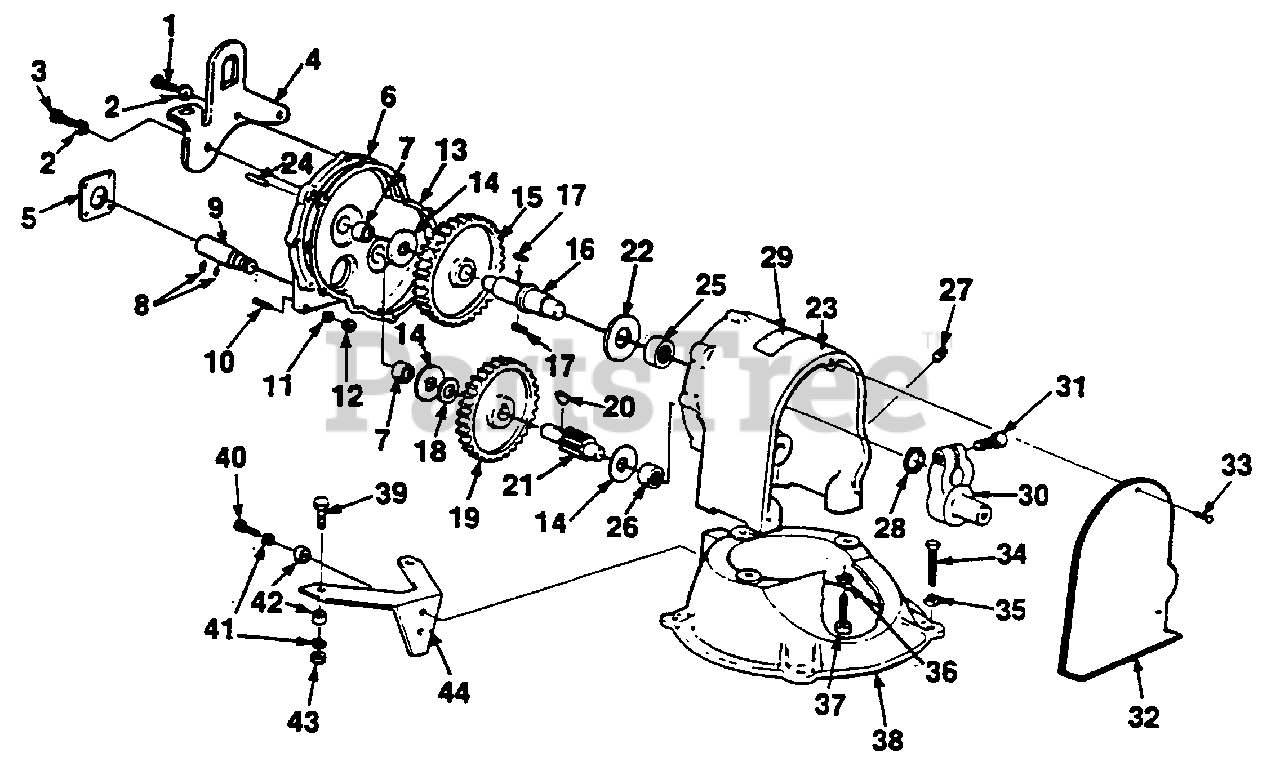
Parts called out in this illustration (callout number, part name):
1	SCREW-Hex hd. (1/4-20 x 1 1/2")
2	WASHER-Lock (1/4")
3	SCREW-Hex hd. (1/4-20 x 1 1/4")
4	BRACKET-Lift
5	GASKET-Engine mounting
6	COVER-Gear Case w/bearings
7	BEARING-Needle
8	SCREW-Set, 10-32 x 3/8 (Nylok)
9	SHAFT-Extension
10	STUD-5/16-24, 5/16-18
11	WASHER-Lock (5/16")
12	NUT-5/16-18
13	GASKET-Gear case
14	WASHER-Thrust, small
15	GEAR-Main
16	SHAFT-Drive
20	KEY-Woodruff, #61
21	SHAFT-Pinion
22	WASHER-Thrust, large
23	CASE-Gear w/bearings
24	PIN-Dowel
25	BEARING-Needle
26	BEARING-Needle
27	PLUG-Pipe
28	SEAL-Garlock
30	CRANK
31	SCREW-Cap (1/2-13 x 1 1/2")
32	SHIELD-Crank
33	SCREW-Thumb (1/4-20 x 1/2")
34	SCREW-Hex hd.
35	WASHER-Lock (3/8")
36	WASHER-Lock (1/2")
37	SCREW-Hex hd. (1/2-13 x 1 3/4")
38	BODY-Pump (upper)
39	SCREW-Hex hd. (5/16-18 x 1 1/2")
40	SCREW-Hex hd.
41	WASHER-Lock (5/16")
42	WASHER-Flat
43	NUT-(5/16-18)
44	SUPPORT-Engine
